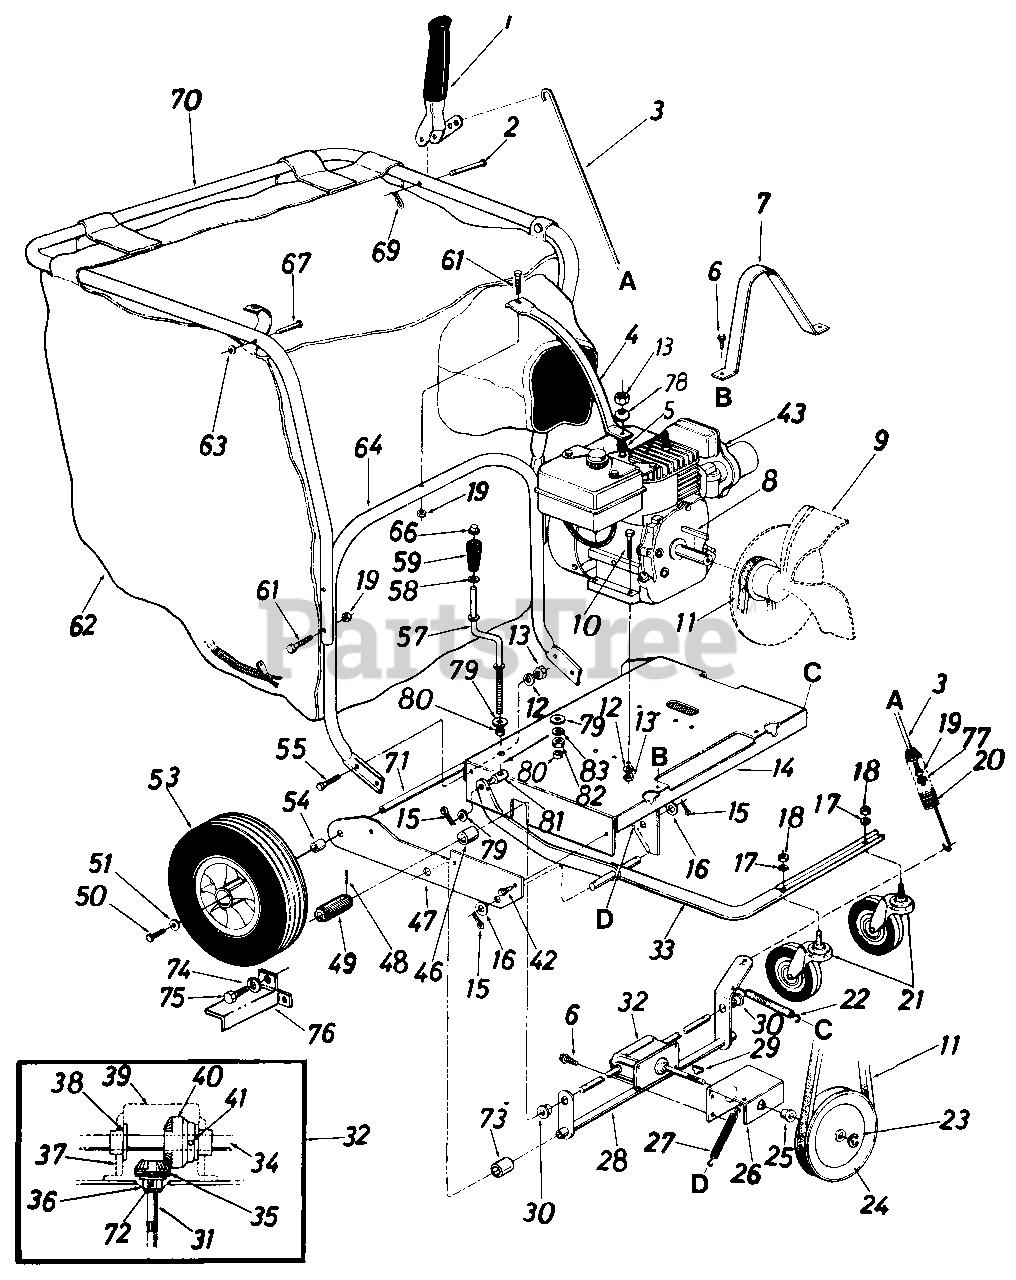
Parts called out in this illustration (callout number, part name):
1	Clutch Grip Ass'y.
2	Clevis Pin .375" Dia. x 1.88"
3	Clutch Rod 32" Lg.
4	Handle Brace (Painted)
5	Part of Engine
6	Hex Wash. Hd. AB-Tap Scr. 1/4" x 62" Lg.
9	Air Vane Plate Ass'y. w/Pulley
10	Hex Bolt 5/16-18 x 1.5" Lg.
11	"V"-Belt
12	L-Wash. 5/16" I.D.
13	Hex Nut 5/16-18 Thd.
16	Fl-Wash. .63" I.D. x 1.25" O.D.
17	L-Wash. 1/2" I.D.
18	Hex Nut 1/2-13 Thd.
19	Hex Cent. L-Nut 1/4-20 Thd.
20	Extension Spring .78" O.D. x .75" Lg.
21	Swivel Caster Wheel 5" Dia. x 1.25"
22	Extension Spring .38" O.D. x 7.50" Lg.
23	Snap "E"-Ring .50" Dia. Shaft
24	"V"-Pulley 5/8" x 6.50" O.D.
25	Flange Bearing .502" I.D.
28	Clutch Bracket Ass'y.
29	#2 Woodruff Key 3/32" Dia. x .81" Lg.
30	Hex Flange Bearing Bronze .625" I.D.
31	Pinion Shaft .50" Dia. x 5"
32	Gear Box Ass'y. Comp.
35	Bevel Gear .50" I.D. x 14 Teeth
36	Flange Bearing .503" I.D.
37	Gear Box
38	Flange Bearing .630" I.D.
39	Gear Box Cover
40	Bevel Gear .62" I.D. x 28 Teeth
41	Spring Pin Spiral 3/16" Dia. x 1.25" Lg.
42	Hex Wash. Hd. AB-Tap Scr. 5/16" x .75" Lg.
43	Engine
46	Spacer .63" I.D. x.88" O.D. x .56" Lg.
49	Drive Pinion
50	Hex Locking Bolt 5/16-24 x .62" Lg.
51	Fl-Wash. .34" I.D. x.87" O.D.
53	Wheel Ass'y. Comp. 12" x 3"
54	Spacer .63" I.D. x 1.0" O.D. x .94" Lg.
55	Hex Bolt 5/16-18 x .75" Lg.
57	Height Adjustment Crank
58	Fl-Wash. .385" I.D. x .62" O.D.
59	Crank Knob
61	Hex Bolt 1/4-20 x 1.75" Lg.
62	Vacuum Bag-Felt
63	Push Speed Nut .25" Dia. Stud
67	Stud Pin .250" Dia. x 1.75"
69	Internal Cotter Pin 3/8" Dia.
70	Upper Handle (Painted)
71	Rear Axle
72	Spring Roll Pin 5/32" Dia. x 1.12
73	Spacer .82" I.D. x 1.0" O.D. x .305 Lg.
74	L-Wash. .265" I.D.
75	Hex Self-Tap Scr. 1/4" x 3/8" Lg.
78	Belleville Washer
79	Fl-Wash. .35" I.D. x.87" O.D.
80	Spacer .38" I.D. x .50" O.D. x .18" Lg.
81	Ferrule 3/8-8 x .38" Dia.
82	Hex Nut 3/8-8 Thd.
83	L-Wash. 3/8" I.D.
